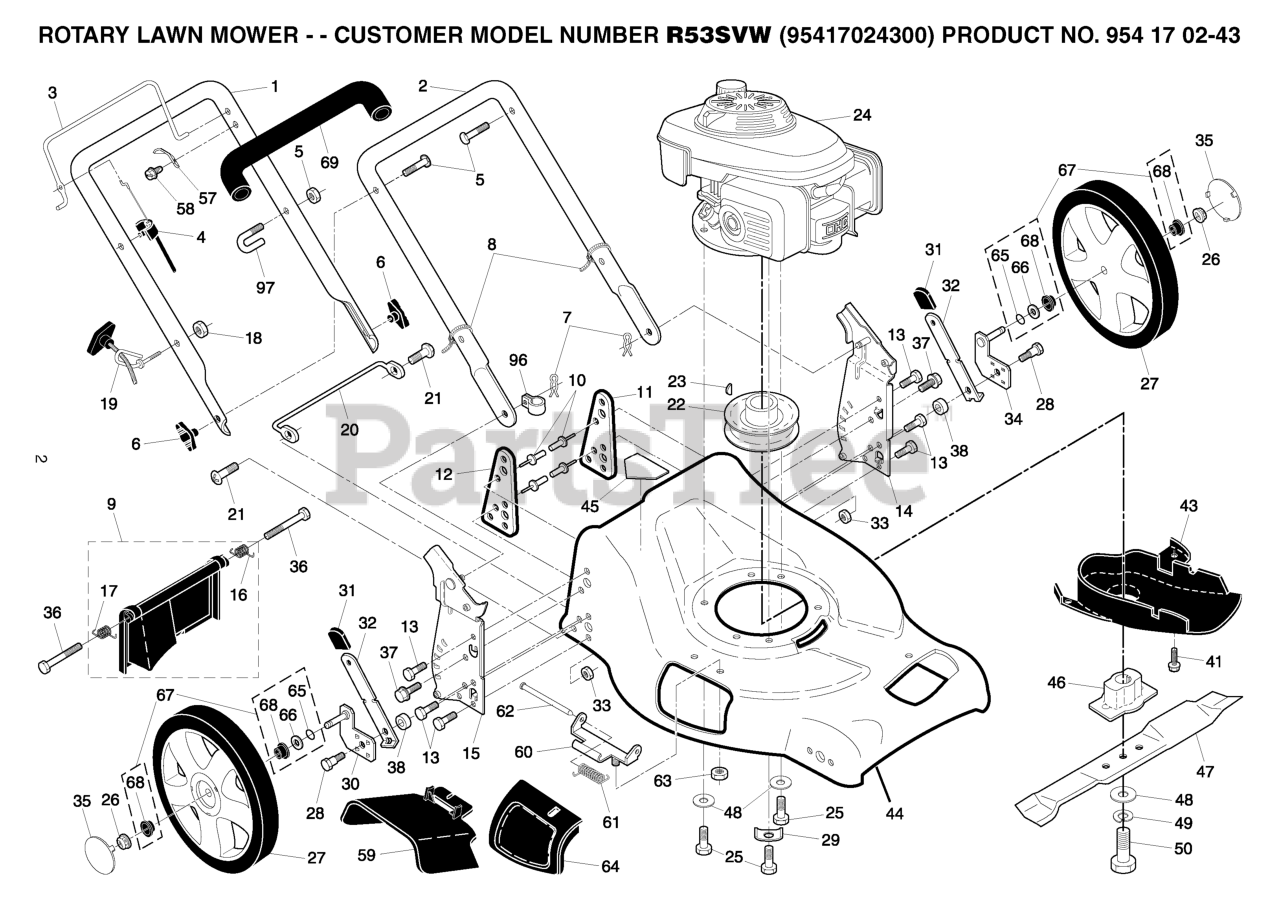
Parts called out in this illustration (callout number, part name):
2	LOWER HANDLE
3	BAIL, FLAT AUTO WALK
4	CABLE.ENGINE BRAKE.MZR
5	BOLT, HANDLE 5/16-18X1.75
6	HNDL.KNOB.GRAY
7	HAIRPIN COTTER
8	TIE GUIDE
9	KIT.DOOR.RR.ASM.21.FWGD
10	RIVET BLIND
11	SUPPORT BRACKET LH
12	SUPPORT BRACKET RH
13	SCREW 14-20 X 5/8
14	BRKT.ASM.HNDL.21FGD
15	BRKT.ASM.HNDL.21FGD.EZ
17	SPRING.REAR.DOOR.EZ.21
18	NUT
19	ROPE, GUIDE
22	ENGINE PULLEY
23	HI-PRO KEY
25	BOLT 3/8-16X1-1/8
26	HEX FLANGE LOCKNT
27	RP WHEEL 14X2
28	SHOULDER BOLT
29	WASHER.ENGINE.BZP
30	AXLE ARM ASSEMBLY RR
31	KNOB, DEFLECTOR
32	SELECTOR SPRING
33	NUT.71038.31-18.HEX.NYLOCK
34	AXLE ARM ASSEMBLY LR
35	HUBCAP
37	SELF-TAPPING SCREW 5/16-18X3/4
38	WASHER.FLAT.34X1.38X22
41	SCREW.HEX.WSH
43	DEBRIS.SHIELD.FWGD.WALK.MOWER
45	DECAL.INTERNATIONL.CUTFINGER
46	BLADE ADAPTER
47	21" PUSH BLADE
48	WASHER,HARDEN
49	LOCKWASHER
50	SCREW, HEX HD 3/8-24 X 1-3/8
57	BRACKET UPSTOP
59	DEFLECTOR.CLIPPIN.21.FGD
60	BRACKET.ASM.HINGE.21.FWGD.
61	SPRING
62	ROD.HINGE.21
63	LOCKNUT.NYLOC.1/4-20
64	DOOR.MULCH.21.REAR.FWGD
65	O-RING
66	WASHER.FLAT.1/2
67	KIT.BUSHING.WHEEL.14"
68	Bushing, Nylon, Black
69	GRIP.HANDLE.FOAM.WIDE.(1 SIDE)
96	CLIP.CABLE.BLK
